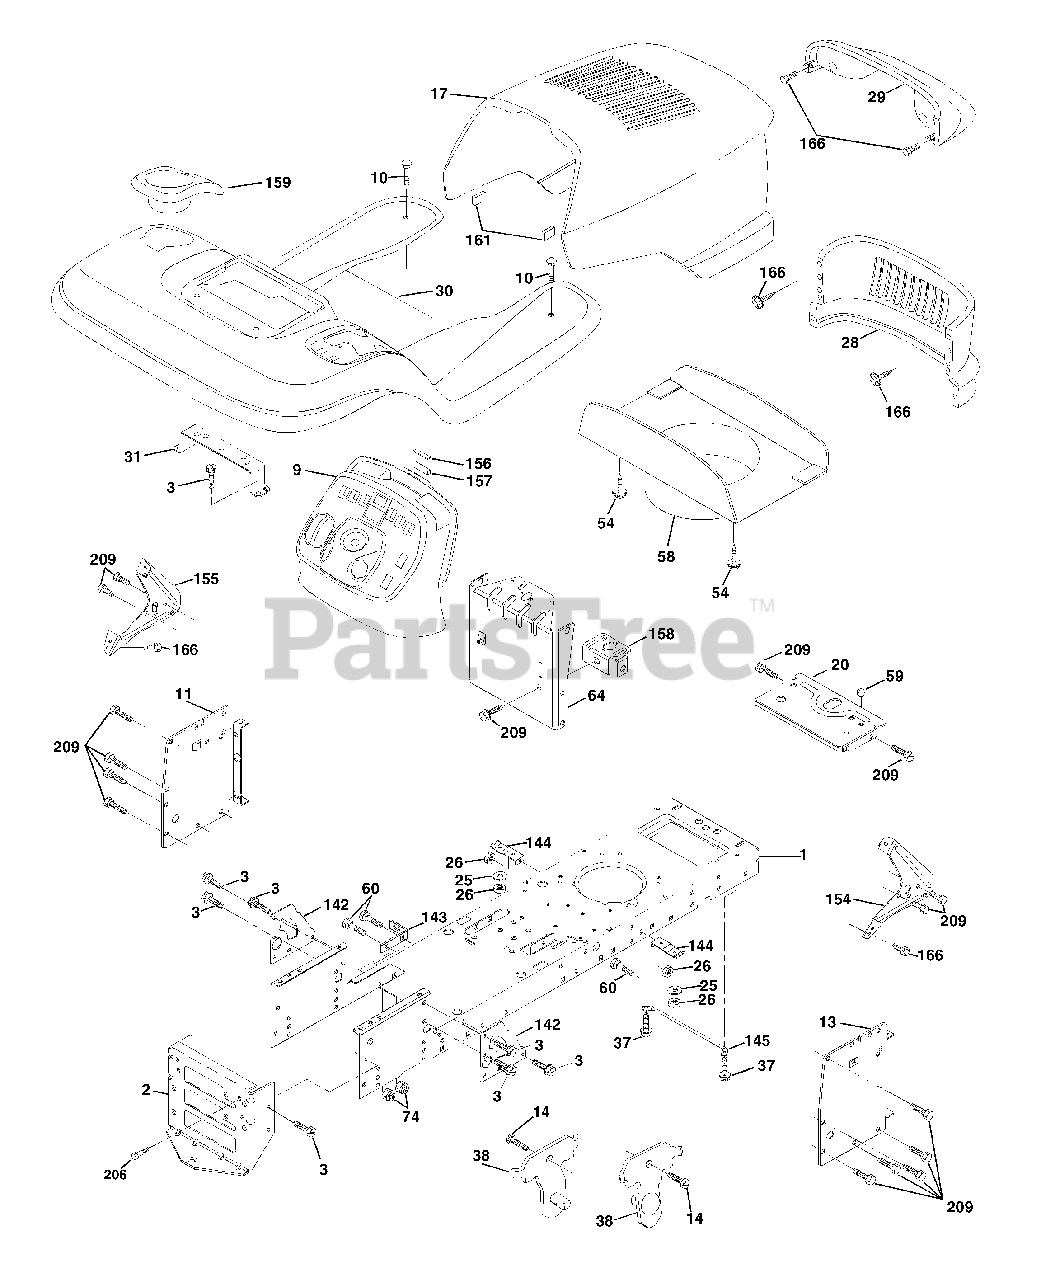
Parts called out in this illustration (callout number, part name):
1	Chassis
2	Drawbar
3	Screw 3/8-16 x 3/4
9	Dash
10	Bolt 3/8-16 x 1
11	Panel Dash Lh
13	Panel Dash Rh
14	Screw Thdrol 3/8-16 x 1/2
17	Hood
20	Plate Battery
25	Washer 13/32 X 13/16 X 12 Ga
26	Nut Lock Hex W/Ins 3/8-16 Unc
28	Grille
29	Light Box Asm w/Lens
31	Bracket Fender
37	Screw Thdrol 6/16-18 x 1/2 TYT
38	Bracket, Asm. Pivot Mower Rear
54	Screw Hex Wshd 8-18 x 7/8
58	Duct Hood
59	Bushing Snap
60	Bolt Rd Hd Sqnk 3/8-16 Unc x 3/4
64	Dash Lower
74	Nut Crownlock 3/8-16 Unc
142	Plate Reinforcement STLT
143	Bracket Swaybar Chassis
144	Bracket Footrest
145	Rod Pivot Chassis/Hood
154	Bracket Dash Rh
155	Bracket Dash Lh
156	Striker Plate
157	Magnet Stealth
158	Bracket Parking Brake
159	Cupholder
161	Extrusion Bumper
166	Screw Hw Hd Hi-Lo #13-16 x 3/4
206	Bolt Shoulder 5/16-18
209	Screw Hexwsh Thdrol 3/8-16 x 3/4
